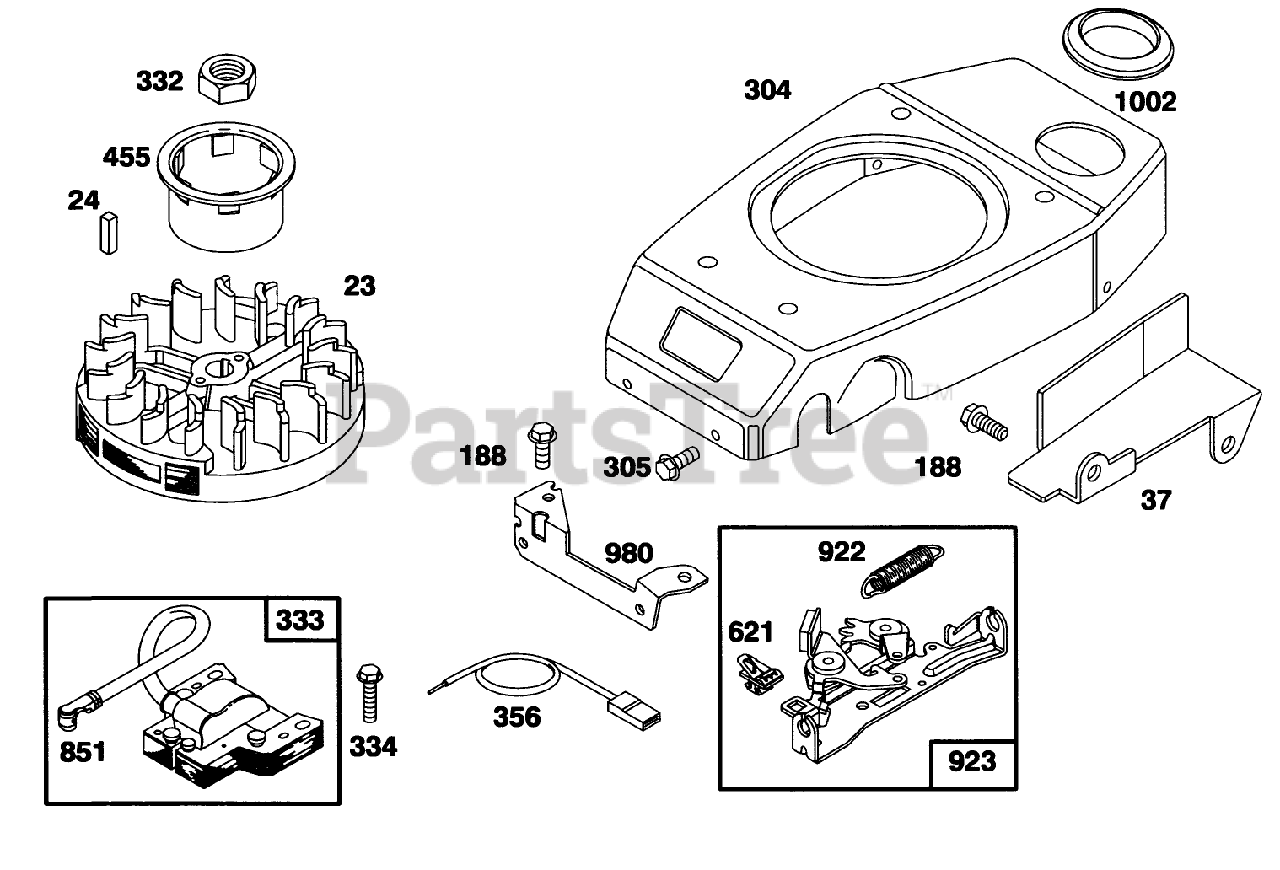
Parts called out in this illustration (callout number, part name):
24	KEY - FLYWHEEL
37	GUARD - FLYWHEEL
304	HOUSING - BLOWER
305	SCREW - HEX HEAD
332	NUT - HEXAGON
356	WIRE - GROUND
621	STOP SWITCH
980	BRACKET-BLOWER HSG
